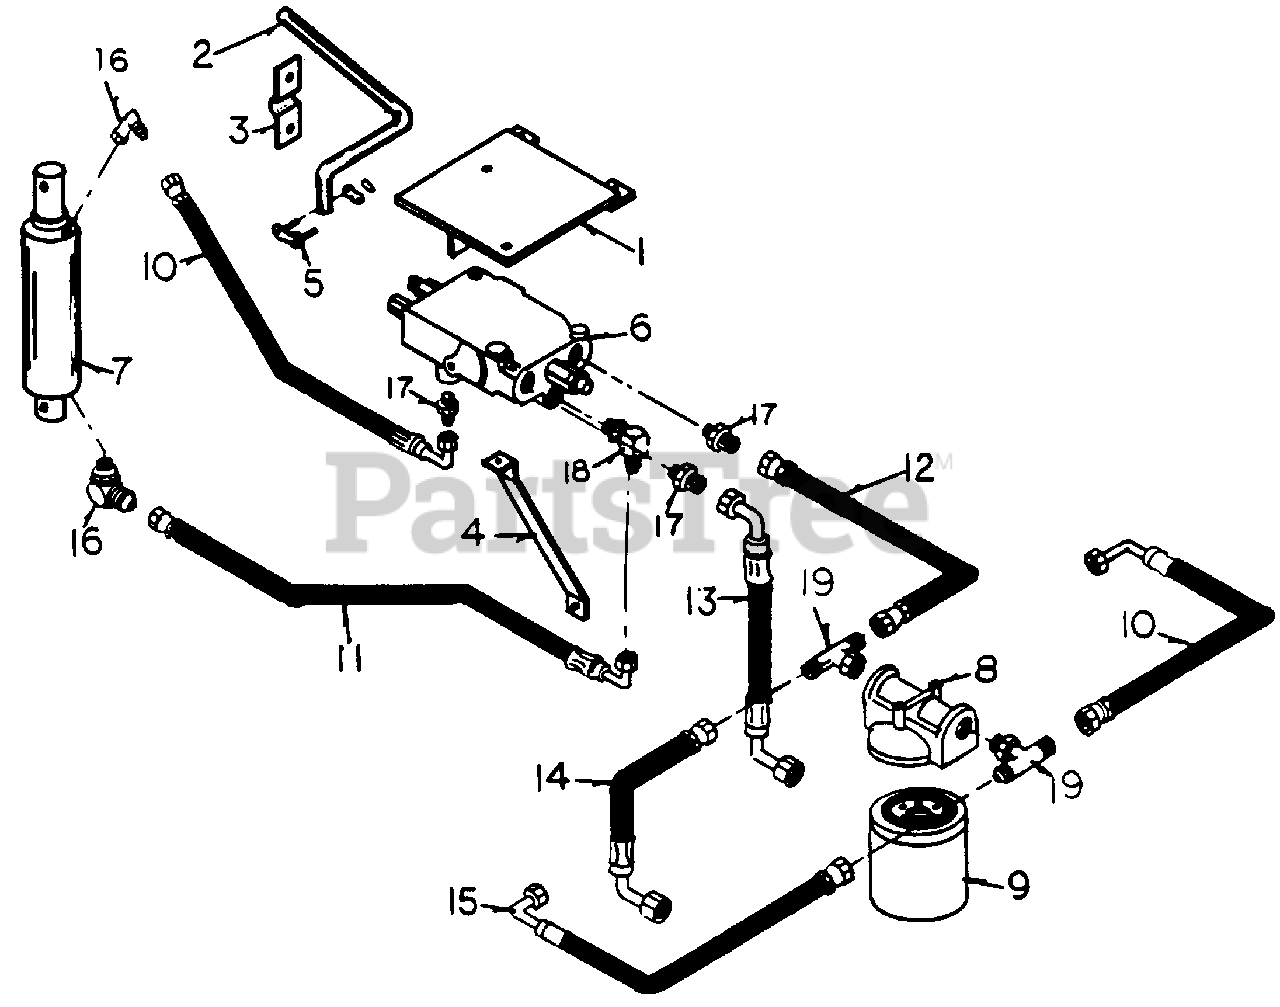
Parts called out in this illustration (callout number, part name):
1	Valve Mount
3	Bearlng, Clutch 8rake Cross Rod
4	Valve Support
5	Connecting Link, #50
8	Housing, 0i1 Filter
9	Element, Oil Filter
10	Hose, 3/8" ID x 26" Long
11	Hoe, 3/8" ID x 31" Long
12	Hose, 3/8" ID x 20" Long
13	Hose, 3/8" ID x 13" Long
14	Hose, 3/8" ID x 11.5" Long
15	Hose, 3/8" ID x 21" Long
16	Male O-ring, 90ø Male Tube Adp.
17	Male O-ring, Male Tube Adp.
18	Male O-ring, 90ø Male Tube Adp.
19	Male Tube, Male O-ring Tee
